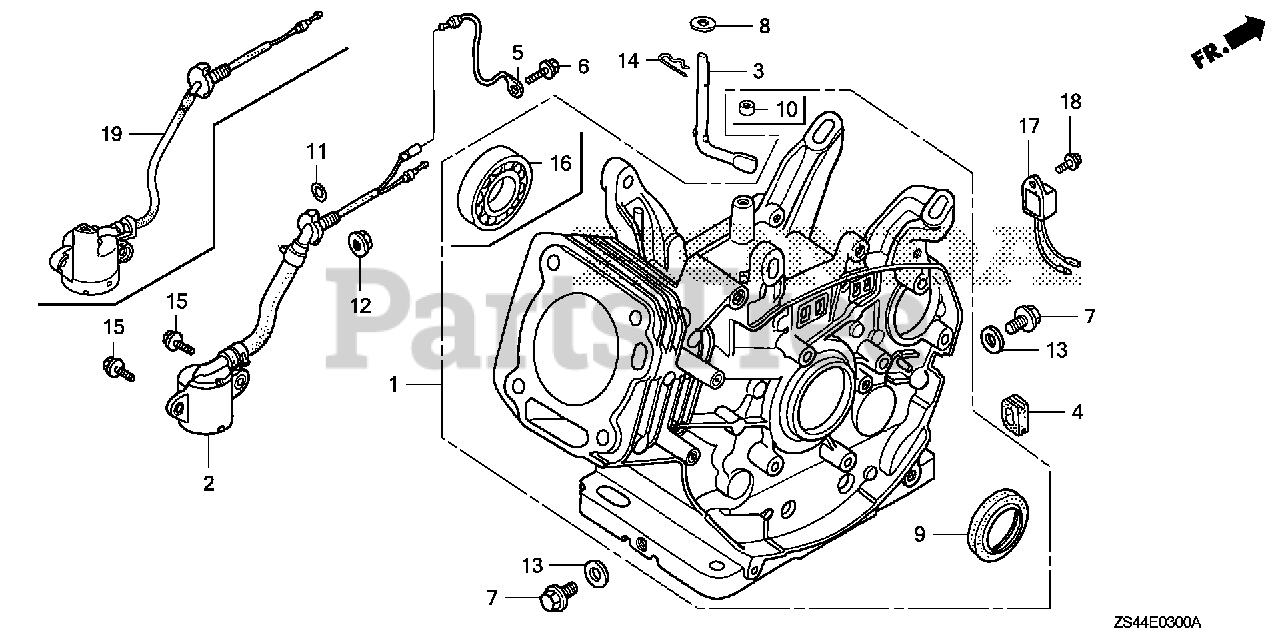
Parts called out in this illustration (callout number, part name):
1	CYLINDER ASSY. (ALERT)
2	SWITCH ASSY., OIL LEVEL
3	SHAFT, GOVERNOR ARM
4	GROMMET, WIRE
5	SUB-HARNESS (NOT AVAILABLE)
6	BOLT, FLANGE (6X12) (CT200)
7	BOLT, DRAIN PLUG (12X15)
8	WASHER (8.2X17X0.8)
9	OIL SEAL (30X46X8)
11	O-RING (13.5X1.5) (ARAI)
11	O-RING (14MM) (NOK)
12	NUT, FLANGE (10MM)
13	WASHER, DRAIN PLUG (12MM)
14	PIN, LOCK (10MM)
15	BOLT, FLANGE (6X12)
17	ALERT UNIT, OIL
18	BOLT, FLANGE (6X12) (CT200)
19	SWITCH ASSY., OIL LEVEL
